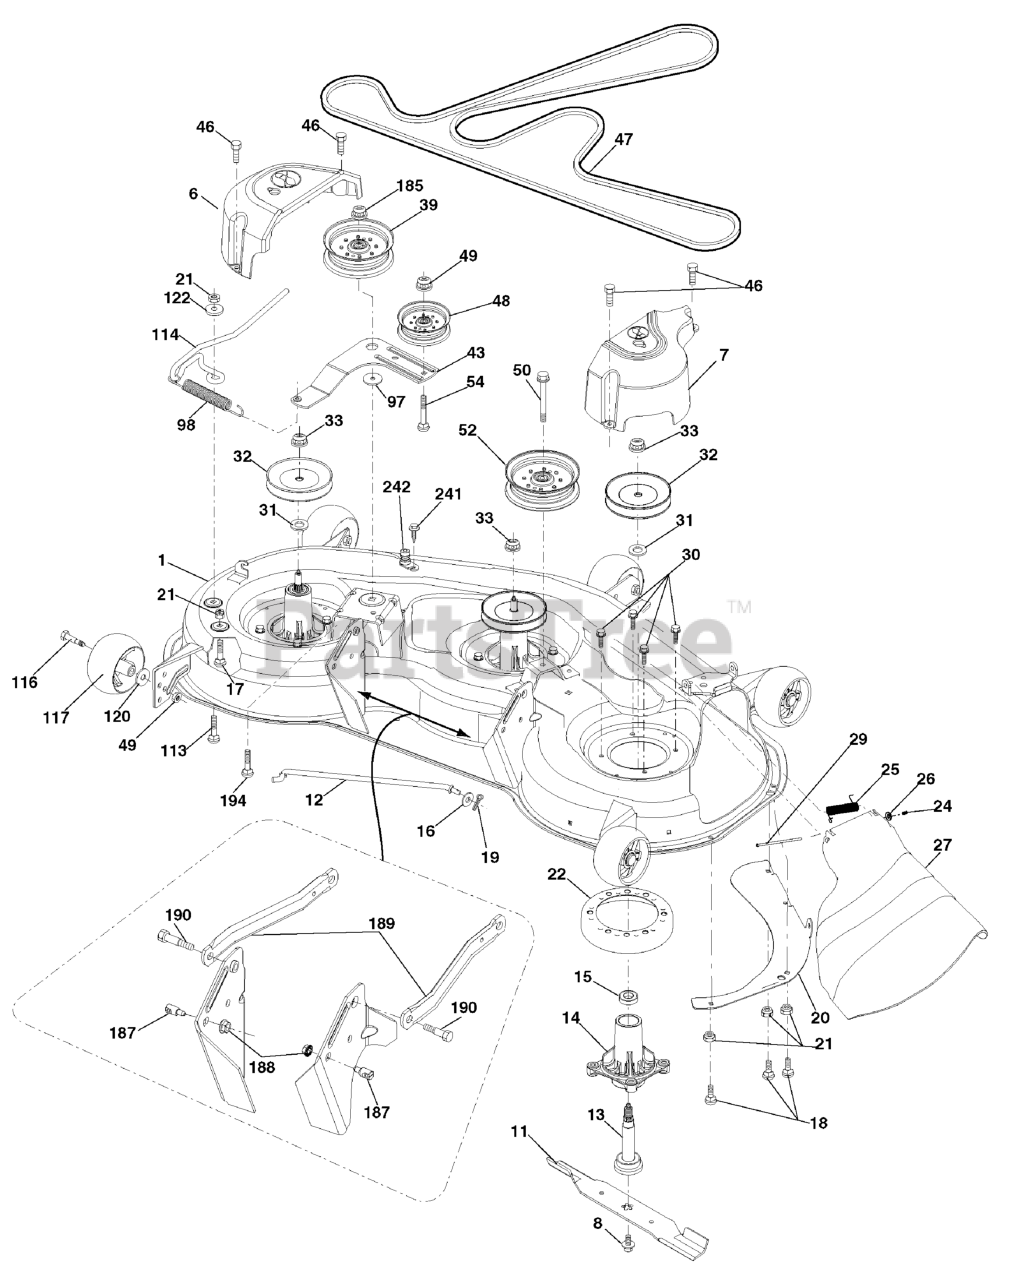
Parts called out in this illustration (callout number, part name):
1	** Deck Weldment Mower
6	Cover Mandrel LH
7	Cover Mandrel RH
8	Bolt 7/16 Asm.
11	** Blade High Lift
12	Rod Anti-Sway
13	** Shaft Asm. w/Lower Bearing
14	Housing, Mandrel
15	Bearing, Ball, Mandrel
16	Washer 13/32 x 13/16 x 12 Ga.
17	Bolt 5/16-18 x 5/8
18	Bolt RdHd 5/16-18 unc x 5/8
19	Pin Cotter 5/16 Bow Tie Lock
20	Baffle Vortex
21	Nut, Crownlock 5/16-18 unc
22	Stripper Mandrel Deck
24	Cap Sleeve
25	Spring, Torsion
26	Nut, Push
27	Deflector Shield
29	Rod, Hinge
30	Screw, Thdroll Washer Head
31	Spacer, Mandrel
32	Pulley, Mandrel
33	Nut, Flg. Top Lock
39	Pulley, Idler
43	Arm, Idler
46	Screw, Thdroll. 1/4-20 x 5/8
47	** Belt Drive Deck
48	Pulley Idler Primary
49	Nut, Lock Flg. 3/8-16 unc
50	Screw 3/8-16 x 2-1/4 unc
52	Pulley Idler
54	Bolt Carr. 3/8-16 x 1-1/2 Gr. 5
97	Washer Hardened
98	** Spring Drive
113	Bolt Rdhd Sqnk 5/16-18 x 3/4
114	Rod Tension Relief
116	Bolt, Shoulder
117	** Gauge Wheel
120	** Washer 13/32 x 1-1/4 x 12 Ga.
122	** Bushing Tension Relief
185	Nut Lock Flange 7/16-14 Gr. 5
187	Stud Fastr. w/"D" Anti-Rotation
188	Nut Lock Hex Flange
189	Arm Susp. Mower Rear
190	Bolt Shoulder
194	Bolt 7/16-14 x 2.25
241	Screw #10-32.5 3/8 Flange
242	* Port Washout
